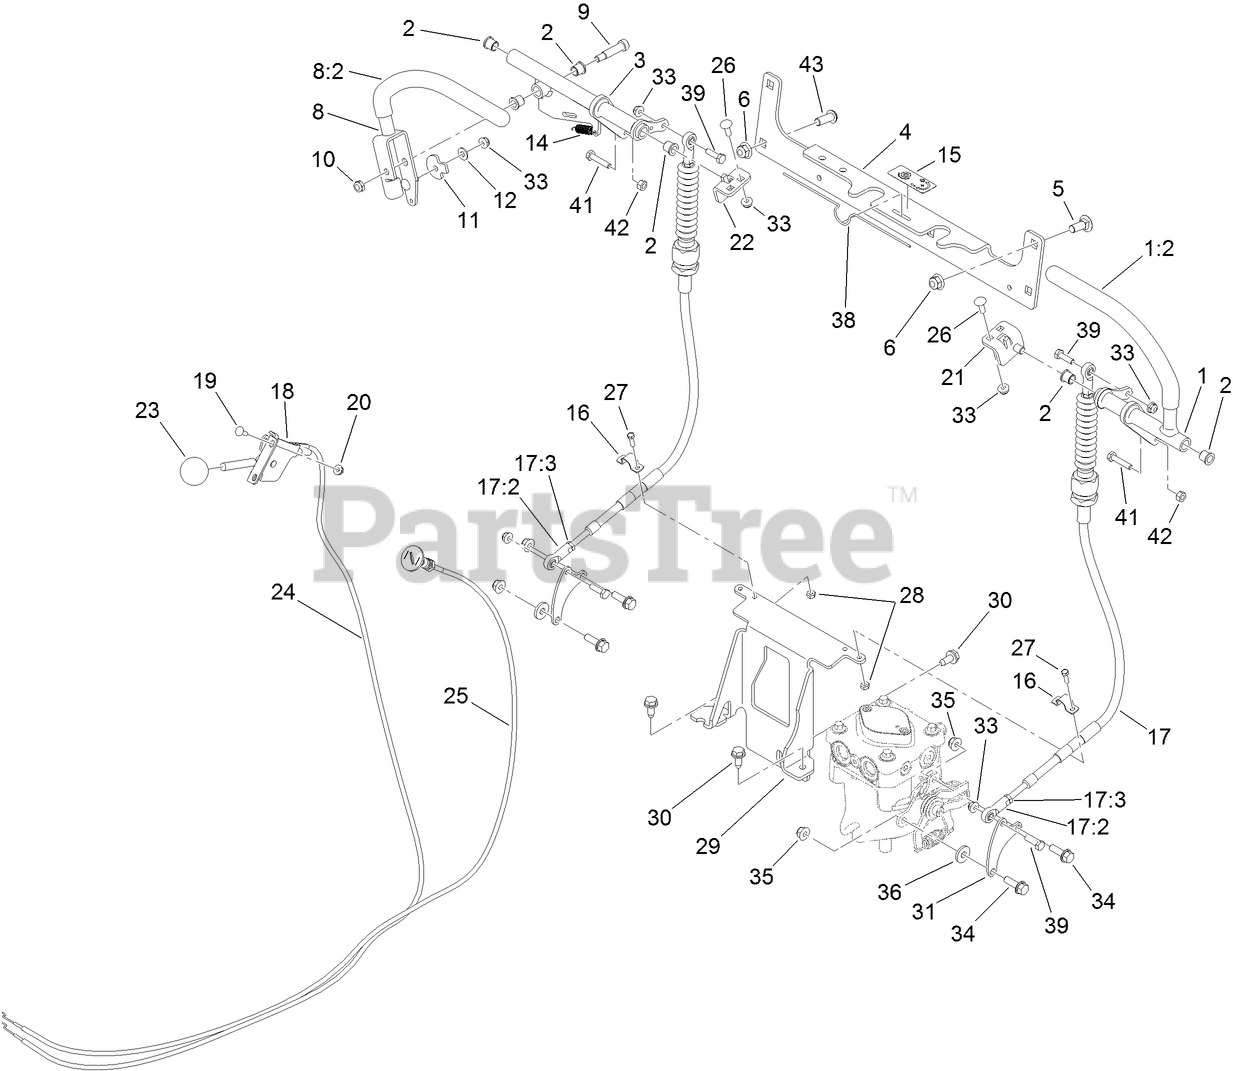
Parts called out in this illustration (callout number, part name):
1	LH LEVER ASM
2	BEARING
3	RH MOTION CONTROL ASM
4	BRACKET-CROSS
5	BOLT-CARR
6	NUT-HF, NI
8	LEVER-MOTION, RH
9	SCREW-HSH
10	NUT-LOCK, NI
11	CAM-LEVER
12	WASHER-FLAT
14	SPRING-EXTENSION
15	DECAL-TRACKING, HYDRO
17	CABLE ASM
17:2	ROD END-BALL JOINT
17:3	NUT-JAM
18	LEVER-CONTROL
19	BOLT-CARR
20	NUT-LOCK, FLANGE
21	LH PIVOT TAB ASM
22	RH PIVOT TAB ASM
23	KNOB-BALL
24	CABLE-THROTTLE
25	CONTROL-CHOKE, PUSH/PULL
26	BOLT-CARR
28	NUT-LOCK, NI
29	BRACKET-CLAMP, CABLE
30	SCREW-HWHTF
31	PLATE-LEVER, PUMP
33	NUT-HF
34	SCREW-HHF
35	NUT-HF, NI
36	WASHER-FLAT
38	CLIP-SPRING
39	SCREW-HH
41	SCREW-HH
42	NUT-HEX
43	SCREW-HSBH
